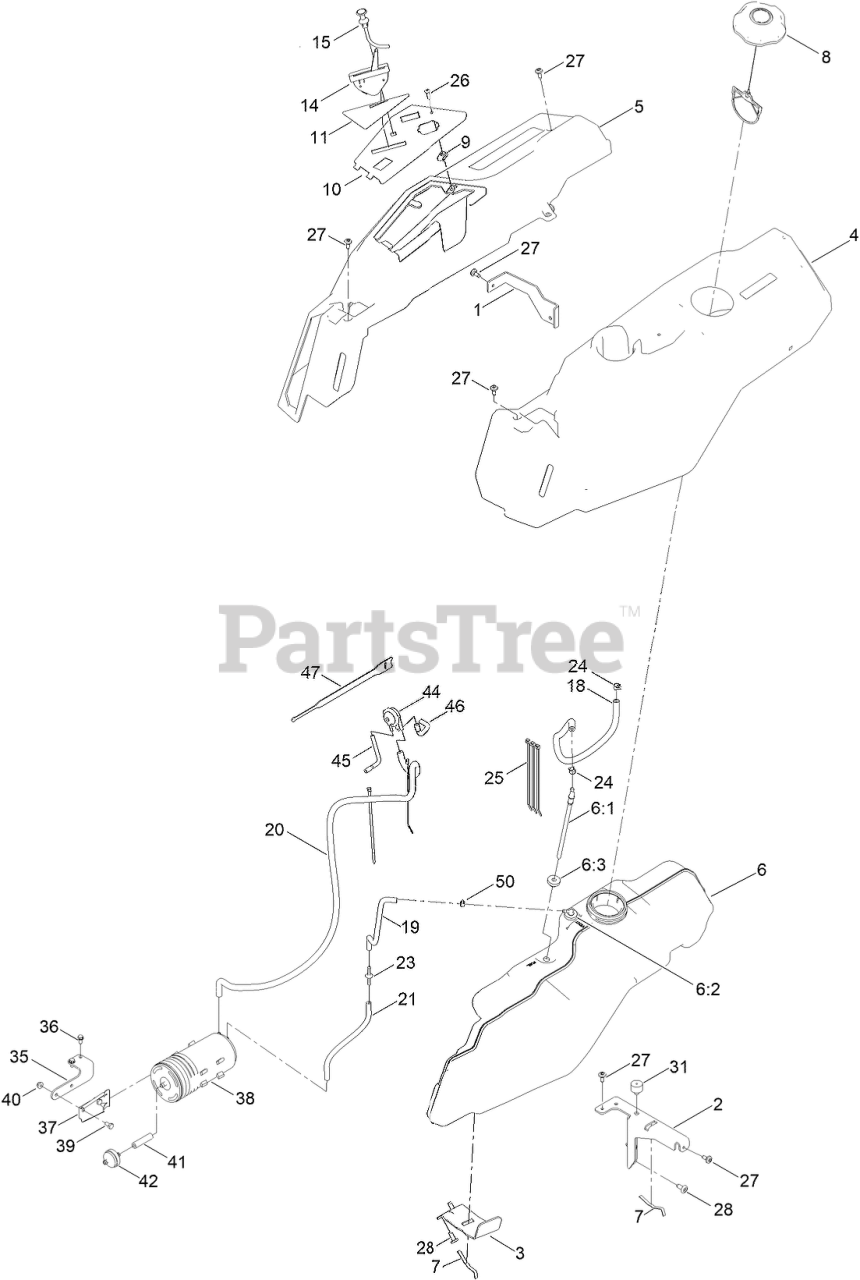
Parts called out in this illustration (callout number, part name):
1	BRACKET-POD
2	SUPPORT-POD, LH
3	SUPPORT-TANK, FUEL
4	POD-LH
5	POD-RH, MYRIDE
6	TANK-FUEL ASM
6:1	CONNECTOR-ELBOW, 90 DEG
6:2	FITTING-ELBOW 90
6:3	BUSHING
7	SPRING
8	CAP-FUEL, RATCHETING
10	PANEL - CONTROL
11	DECAL-PANEL, CONTROL
14	CABLE-THROTTLE
15	CABLE-CHOKE
18	HOSE-FUEL
19	HOSE-FUEL
20	HOSE-FUEL
21	HOSE-FUEL
23	ADAPTER ORIFICE
24	CLAMP-HOSE
25	TIE-CABLE
26	SCREW-PRH
27	SCREW-SHOULDER
31	BUMPER-GROMMET
35	BRACKET-CANISTER, CARBON
36	SCREW-HWH
37	BRACKET-CANISTER, CARBON
38	CANISTER-CARBON, 800CC
39	SCREW-HH
40	NUT-HF
41	HOSE-FUEL
42	FILTER-FUEL, INLINE
44	VALVE-CONTROL, VACUUM
45	HOSE-VENT, FORMED
46	HOSE-VENT, FORMED
47	STRAP-VELCRO, CABLE TIE
50	CLAMP-HOSE
